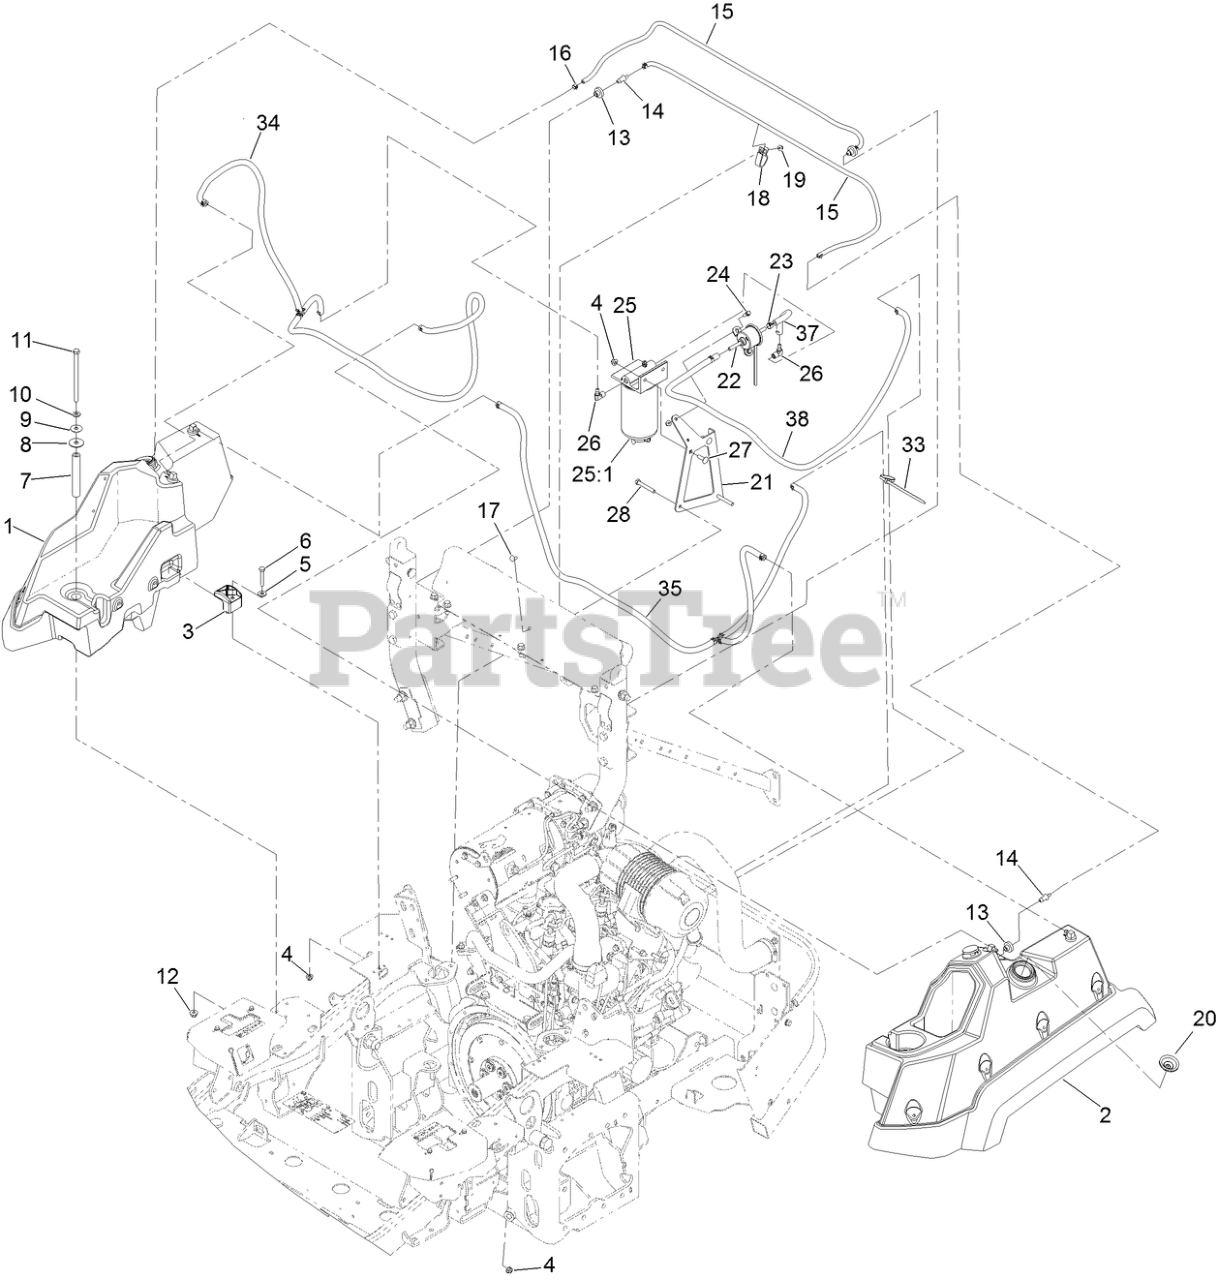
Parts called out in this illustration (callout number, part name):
1	RH FUEL TANK ASM
2	LH FUEL TANK ASM
4	NUT-HF, NI
5	WASHER-FLAT
6	SCREW-HH
7	TUBE-SPACER
8	WASHER-RUBBER
9	WASHER-PLAIN
10	WASHER-FLAT
11	SCREW-HH
12	NUT-HF, NI
13	BUSHING
14	FITTING-ORIFICE, STRAIGHT
15	HOSE-VENT, TANK
16	CLAMP-HOSE
17	SCREW-CARR
18	CLAMP-HOSE
19	NUT-HF
20	CAP-FUEL, DIESEL
21	BRACKET-FILTER, FUEL
22	PUMP-FUEL, ELECTRIC
23	CLAMP-HOSE
24	SCREW-HWH
25	SEPARATOR FILTER ASM
25:1	FILTER-FUEL/WATER SEPARATOR
26	FITTING-HYD, 90
27	SCREW-CARR
28	SCREW-HH
33	TIE-PLASTIC
34	FUEL SUCTION LINE ASM
35	FUEL RETURN LINE ASM
37	HOSE-FUEL
38	HOSE-FUEL
